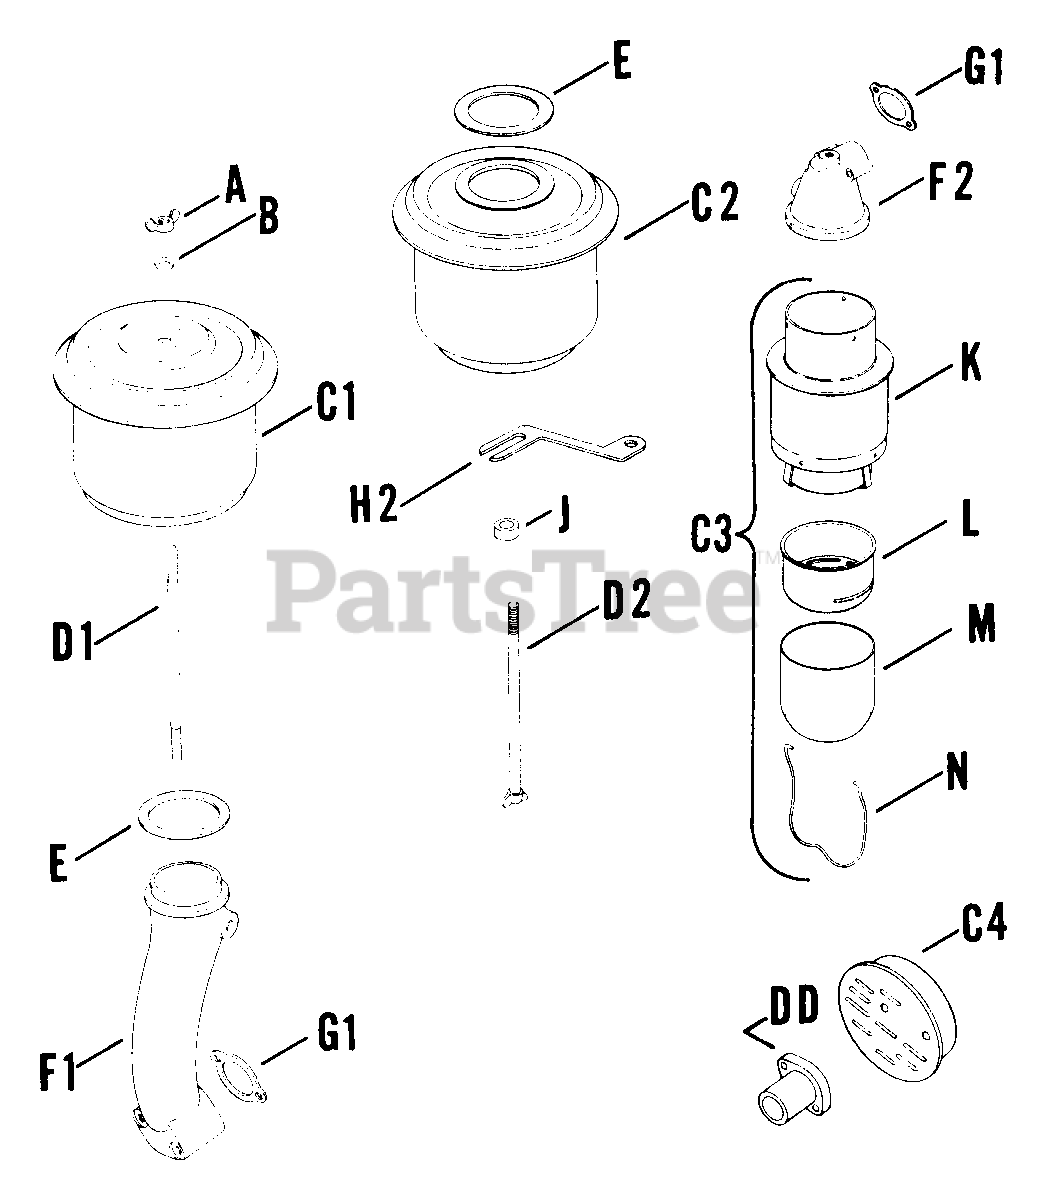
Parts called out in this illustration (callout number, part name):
A	NUT, WING 1/4-20 USE 25 100 15-S
C1	CLEANER
D1	STUD,1/4-20x6-1/4" - DISC.
F1	ELBOW - DISCONTINUED
G1	GASKET - USE 41 041 11
